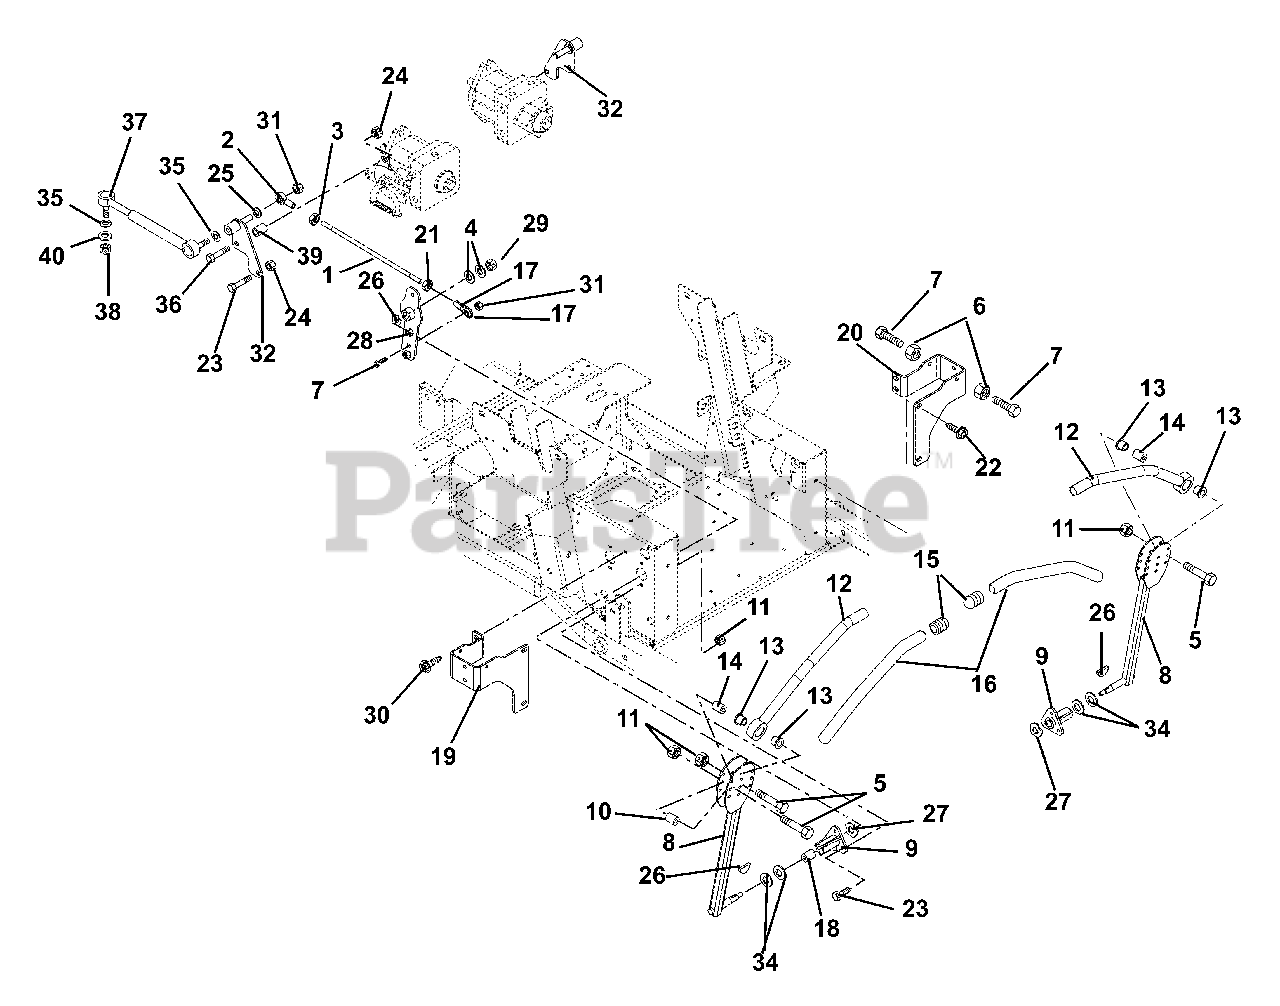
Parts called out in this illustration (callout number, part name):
1	ROD, TIE
2	ROD END, .38 RH
3	NUT-JAM .375-24 YWZC
4	@WSHR-FL-STL.406X.812X.065 YWZ
5	@BLT-HEX .31-18X1.75 GR5 YWZC
6	NUT-HEX-JAM .375-16 YWZC
7	BLT-HEX .375-16X1.750 FTD YWZC
8	CONTROL ARM WELDMENT - BLACK
9	BUSHING, FLANGE
10	ECCENTRIC
11	@NUT-LK-TOP-FLG .31-18 YWZC
12	HANDLE WLDMT LH
13	BSHG-FLG .762X1.48X.44 NYL
14	SPACER .328 X .76 X 1.01
15	CAPLUG - HANDLEBAR
16	GRIP - HANDLEBAR
17	END, ROD-.38 LH
18	BSHG .625X.750X.500
19	RH STOP BRACKET - BLACK
20	LH STOP BRACKET - BLACK
21	NUT-JAM .375-24 LH YWZC
22	@SCR-TAP .38-16X.75 HWH TR YWZ
23	@BLT-HEX .31-18X.75 GR5 YWZC
24	@NUT-LK-TOP-FLG .31-18 YWZC
25	@WSHR-LK .38X.094 REG YWZC
26	KEY-WDRF .13X.63 HRD#5
27	WAVE WASHER .640X.875X.125FH
28	WMT, PIVOT ARM
29	@NUT-LK-TOP-FLG .38-16 YWZC
30	@SCR-TAP .38-16X.50 HWH TR YWZ
31	@NUT-LK-CTR-JAM .375-16 YWZC
32	WMT, RTN/DAMPER/ROD END
33	@BLT-HEX .38-16X1.25 GR5 YWZC
34	WSHR-FL-STL .630X1.005X.062 YZ
35	@WSHR-LK .31X.078 REG YWZC
36	@BLT-HEX .31-18X1.25 GR5 YWZC
37	DAMPENER
38	@NUT-LK-NYL M8-1.25 YWZC
39	SPACER .318X.430X.375
40	@WSHR-FL-STL.38X.875X.083 YWZC
